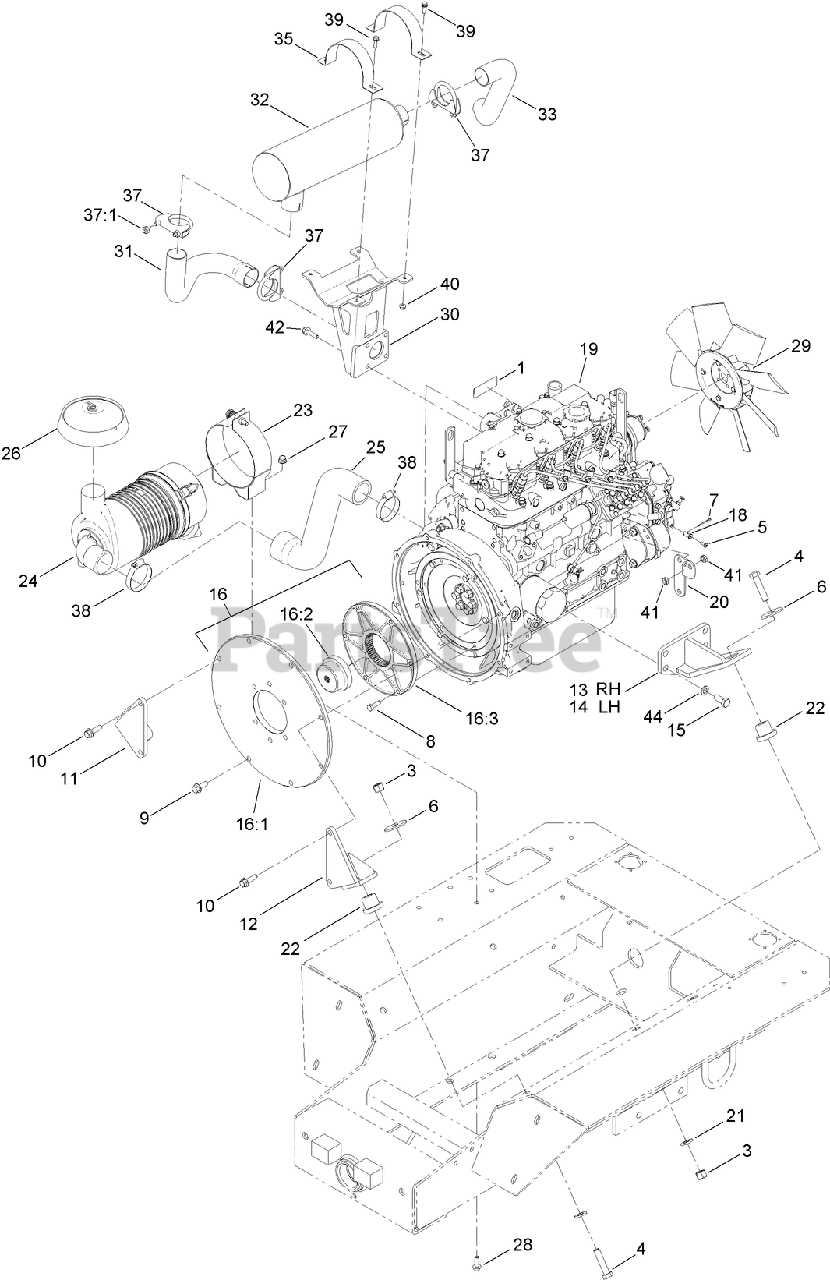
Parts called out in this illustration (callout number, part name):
1	DECAL-DANGER, STARTER FLUID
3	NUT-HEX
4	SCREW-HH
5	SCREW-PPH
6	WASHER-FLAT
7	PIN-COTTER
8	SCREW-HH
9	SCREW-HHF
10	SCREW-HHF
11	MOUNT-ENGINE, LEFT REAR
12	MOUNT-MOTOR, RH
13	MOUNT-ENGINE, FRONT (RH)
14	MOUNT-ENGINE, FRAME (LH)
15	SCREW-HH
16	PUMP DRIVE COUPLER KIT
16:1	PLATE-MOUNTING, PUMP
16:2	HUB-9T
16:3	FLANGE-FLYWHEEL
18	PIN-THROTTLE
19	ENGINE-TIER 4I
20	BRACKET-CABLE, THROTTLE
22	MOUNT-RUBBER
23	BAND-AIR CLEANER
24	AIR CLEANER ASM
25	HOSE-AIR INLET
26	HOOD-RAIN
27	NUT-TORQUE, PREVAILING
28	SCREW-HH
30	SUPPORT-MUFFLER
31	TUBE-EXHAUST
32	MUFFLER-EXHAUST
33	TUBE-EXHAUST
35	BRACKET-MUFFLER
37	CLAMP-MUFFLER
37:1	NUT-JAM
38	CLAMP-HOSE
39	SCREW-HHF
40	NUT-HF
41	NUT-HJ
42	SCREW-HHF
44	WASHER-LOCK
